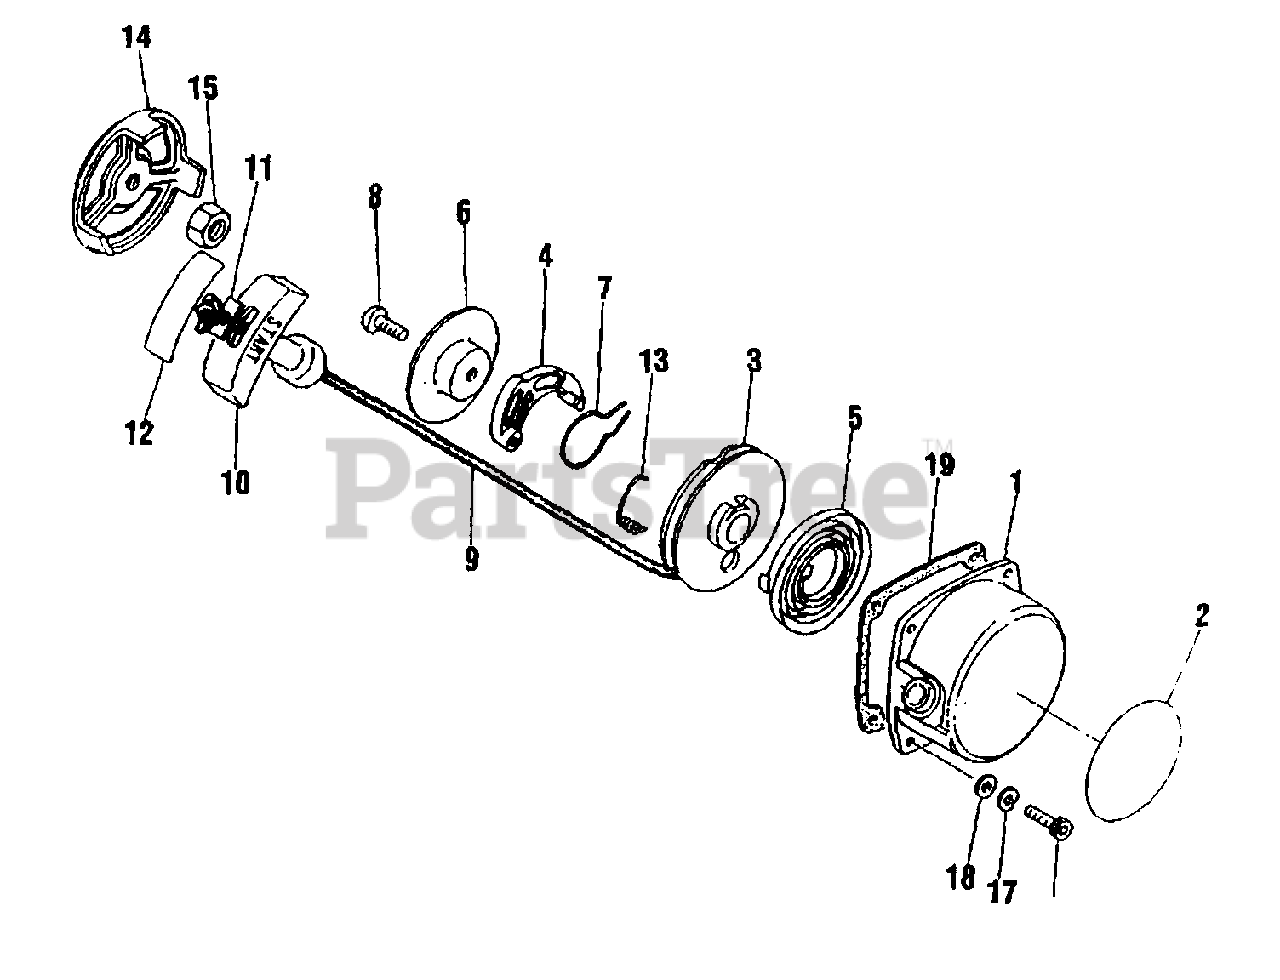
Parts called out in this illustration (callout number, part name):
1	CASE, RECOIL STARTER
3	REEL, ROPE
4	RATCHET
5	SPRING, RECOIL
6	PLATE, FRICTION
7	SPRING, FRICTION
8	SCREW
9	ROPE, STARTER
10	GRIP, STARTER
11	RETAINER, ROPE
12	TAPE
13	SPRING, RETURN
14	PULLEY, STARTER
15	NUT M8×H5
16	BOLT
17	WASHER, SPRING 4 MM
18	WASHER 4 MM
19	GASKET, RECOIL STARTER
